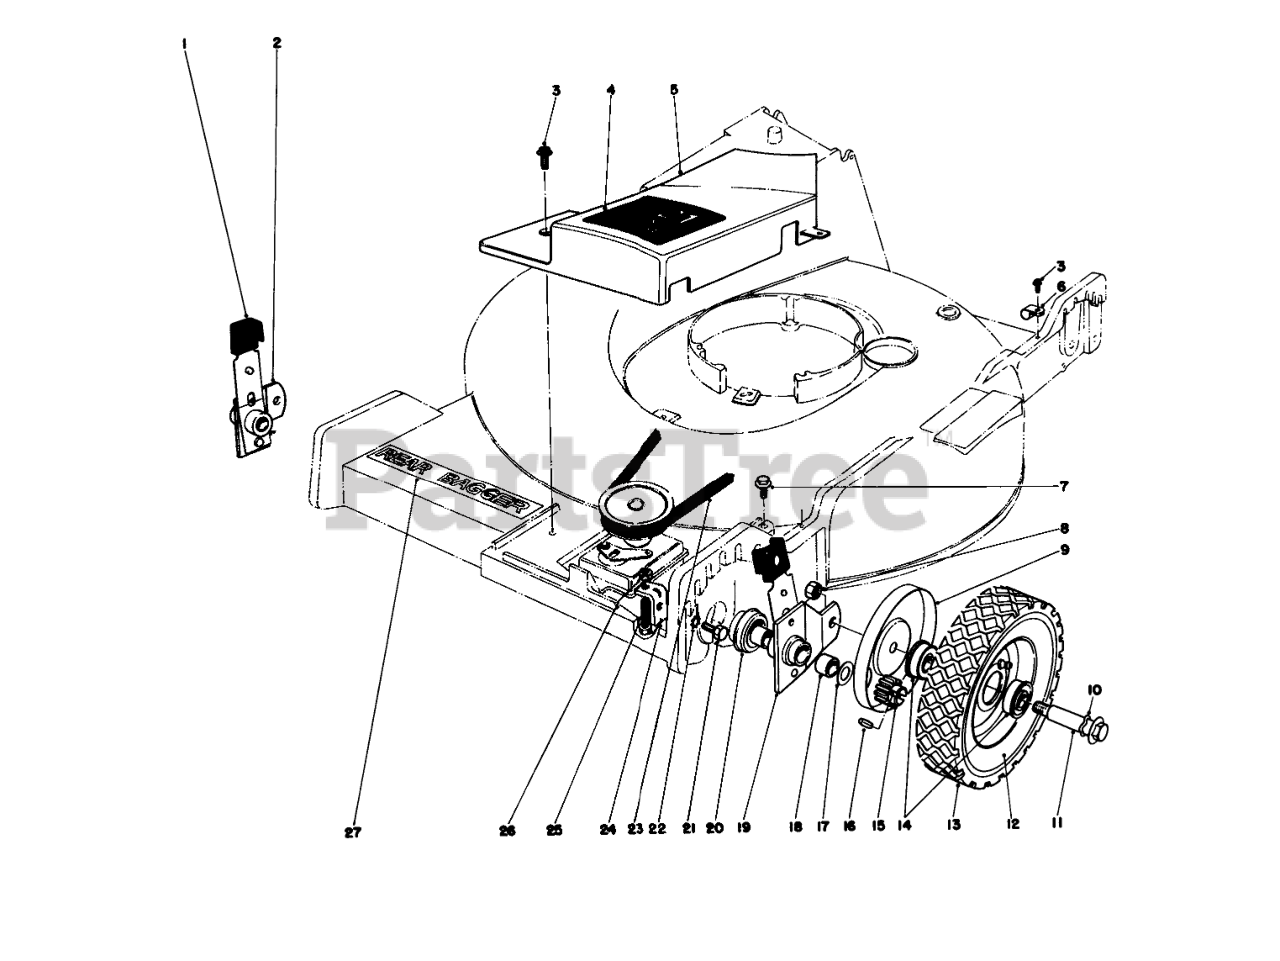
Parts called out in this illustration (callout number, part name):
1	KNOB-ARM
2	Pivot Arm Assembly (Incl. Ref. #17)
3	SCREW
4	Decal Belt Cover
5	BELT COVER
6	CLAMP-NYLON
7	SCREW-HWHTF
8	Nut
9	WHEEL COVER
10	SPRING WASHER
11	WHEEL BOLT
12	Wheel & Tire Assembly (Incl. Ref. #13 & 14)
14	BEARING-BALL
15	Pinion
16	PIN-GROOVED
17	WASHER-THRUST
18	BUSHING
19	Pivot Arm Assembly (Incl. Ref. #18)
20	End Cap
21	SCREW-HH
22	WASHER-LOCK
23	V-BELT
24	Bracket-Gear Box
25	SCREW
26	NUT-LOCK
27	DECK DECAL
